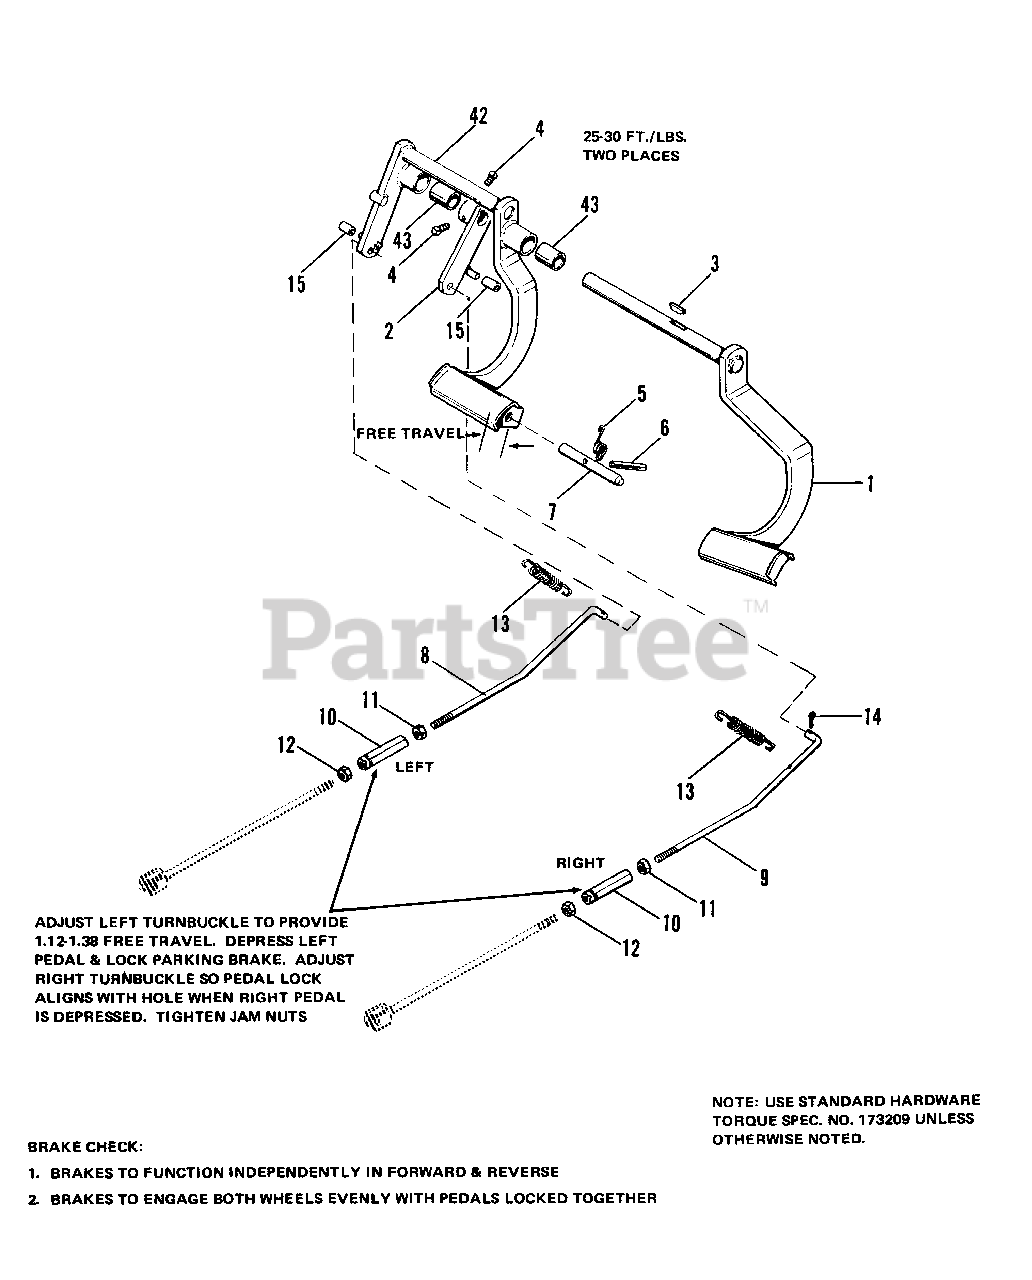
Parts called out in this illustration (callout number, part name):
1	LEVER ASSY, Brake, R.H.
2	BRAKE ANCHOR ASSY
4	SCREW, Set, Sq. Hd.
5	SPRING, Torsion
6	PIN, Spring, 3/16 x 1-3/4
7	ROD, Pedal, Lock
8	ROD, Brake, Front,
9	ROD, Brake, Front, R.H.
10	TURNBUCKLE, Body
11	NUT, Hex, Jam, 3/8-24, L.H.
12	NUT, Hex, Jam, 3/8-24, R.H.
13	SPRING
14	PIN, Cotter, 3/32 x 3/4
15	STOP, Rubber
42	BRAKE LEVER ASSY, L.H.
